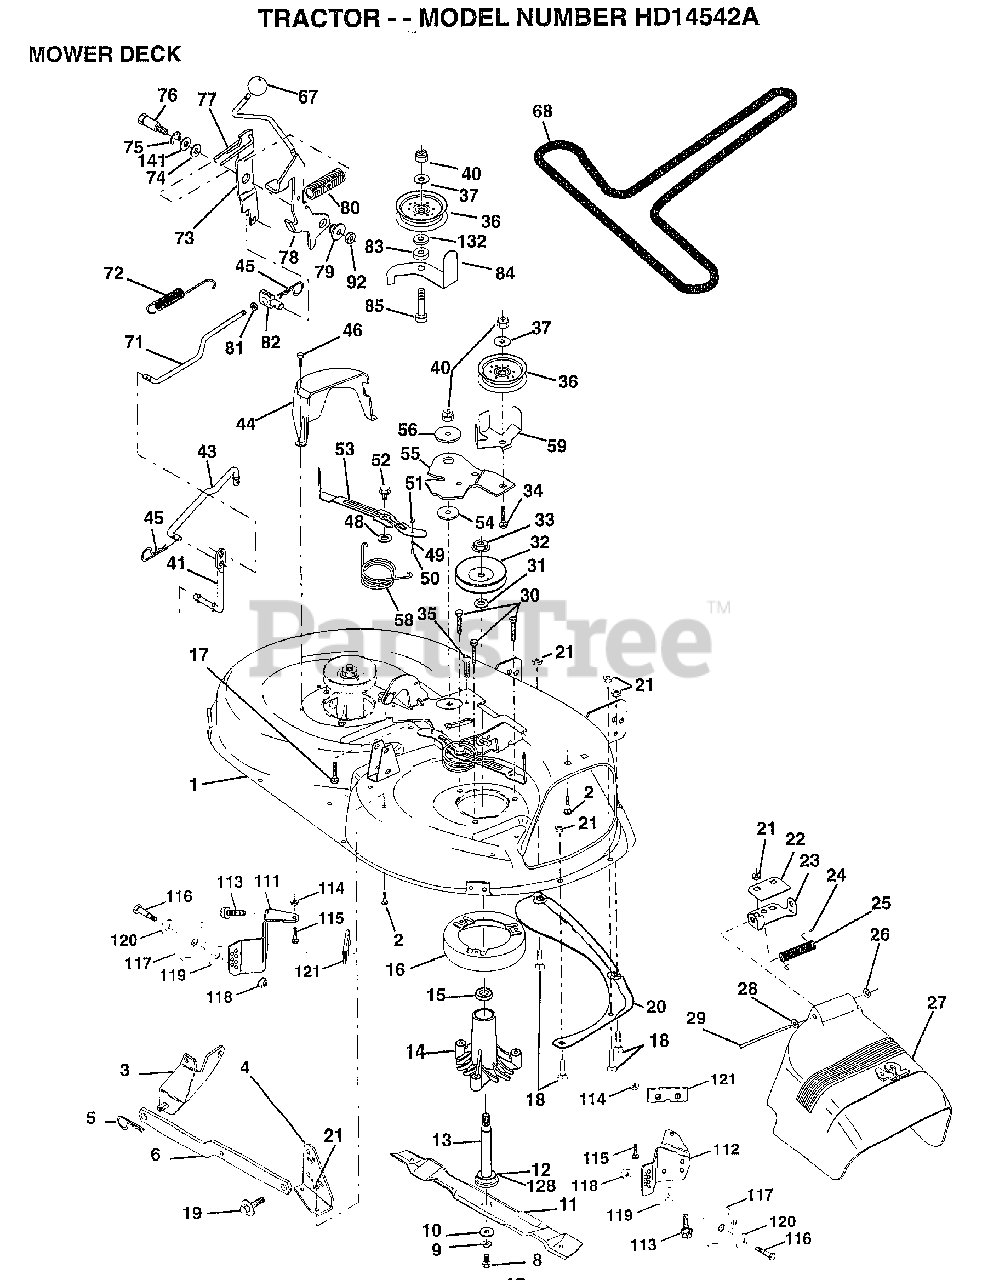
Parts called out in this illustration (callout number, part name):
1	"HOUSING ASSY.42"""
2	BOLT
3	BRKT ASM SWAY BAR
4	BRKT DECK SW BAR
8	BLADE BOLT
10	WASHER.HARD.BLADE
11	"BLADE.42"" HIPERF"
12	BEARING.BALL
14	HSG ASM MANDREL
15	BEARING
16	STRIPPER RND MWR
17	BOLT RDHD 3/8-16
18	BOLT
19	BOLT SHD 5/16-18
20	BAFFLE VORTEX 42
22	STIFFENER BRKT
23	DEFLECTOR BRKT
24	CAP-SLEEVE LT
25	SPRING TORSION
26	NUT PUSH M
27	DEFLECTOR.SHIELD
28	WASHER
29	HINGE ROD
30	"SCREW-THD ROLL,WA"
31	WASHER
32	PULLEY.MANDREL.42
34	BOLT
35	XMAS TREE FASTNER
36	FLAT IDLER PULLEY
37	WASHER
41	PIVOT ROD
43	ROD CLUTCH W/NIBS
44	GUARD MAND LH BLK
45	RETAINER M
46	SCREW.1/4-20X5/8
48	HARD SMALL WASHER
49	ROLLER ASM-CAM
50	SHOULDER BOLT
51	LOCKNUT
52	BOLT.SHLD.5/16-18
53	BRAKE PAD ARM ASM
54	HARDENED WASHER
55	ARM-IDLER
56	SPACER RETAINER
58	SPRING TORSN BRAK
59	GUARD IDLER TUV
67	KNOB.RD.7/16-14
68	BELT.V.T-PATH
71	ROD CLUTCH 38/42
72	RETURN SPRING
73	CLUTCH ARM SECOND
74	WASHER
75	RING
76	SHOULDER BOLT
77	SPRING KEEPER
78	LEVER.ASM.CLUTCH
79	BUSHING
80	SPRING.CLUTCH.MWR
81	NUT
82	TRUNION ADJ
83	WASHER
84	"KEEPER-BELT,FIXED"
85	BOLT
92	NUT
111	BRACKET.GWHL.LH.
112	BRACKET.GWHL.RH.
113	SCREW
116	BOLT M
117	WHEEL.GAGE.BLK.PL
118	LOCKNUT
119	WASHER
120	WASHER
121	BRACKET.EXTRD.GWL
128	WASHER.FELT.
132	WASHER GT
141	WASHER .T
